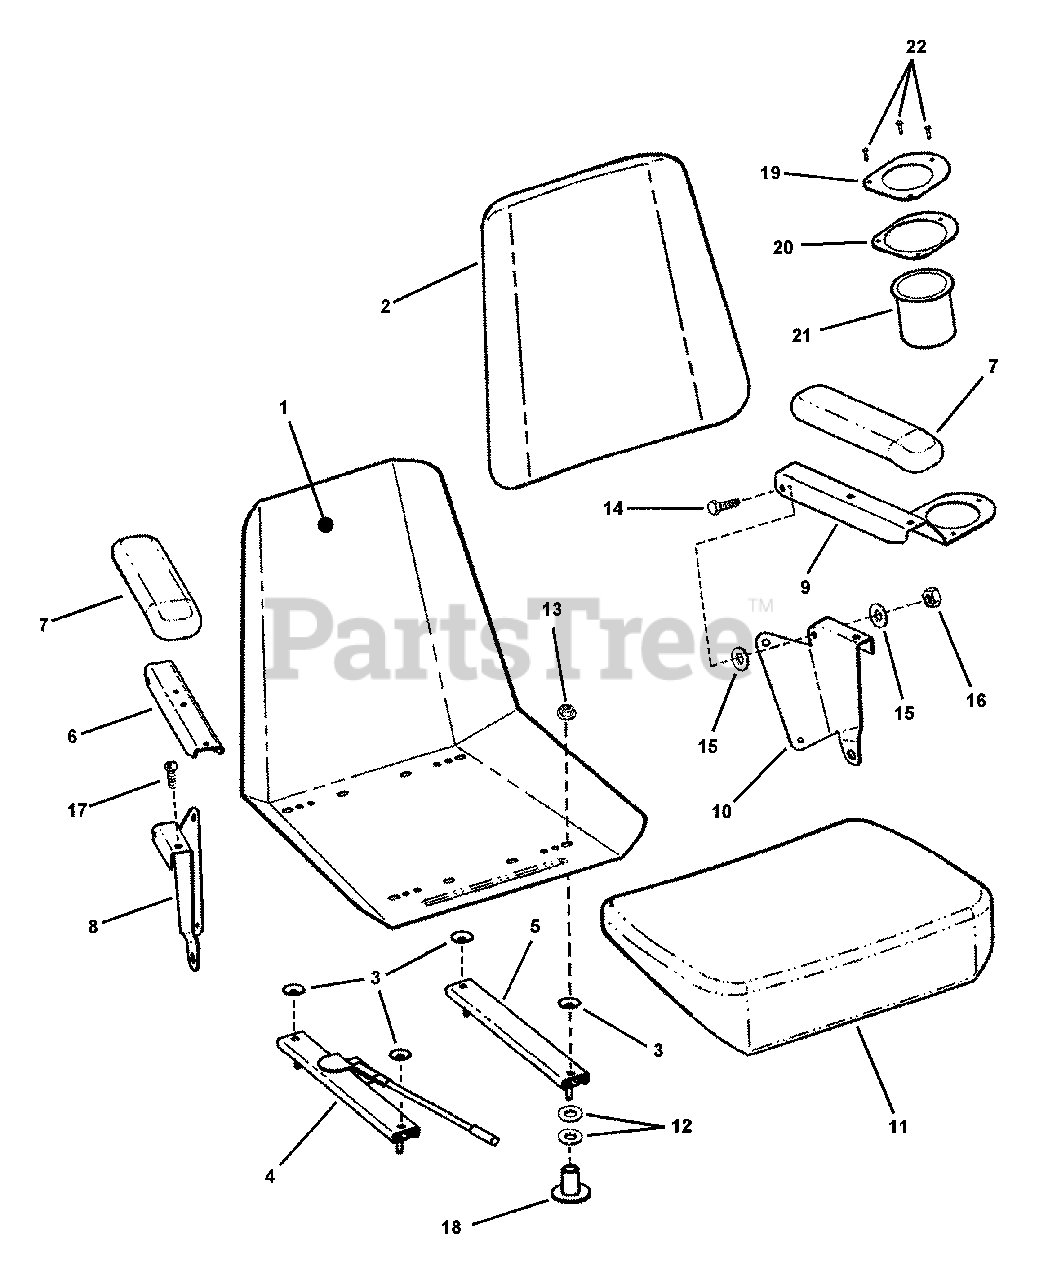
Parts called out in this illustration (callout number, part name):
1	PAN, Seat
2	SEAT CUSHION, Back
3	SPACER, Bell
4	SLIDE ADJUSTER, Seat (w/lock)
5	SLIDE ADJUSTER, Seat (w/o lock)
6	CHANNEL, Armrest
7	PAD, Armrest
8	BRACKET RH, Armrest
9	BRACKET, Armrest Cup Holder
10	BRACKET LH, Armrest
11	SEAT CUSHION, Bottom
12	WASHER, 11/32"
13	NUT, 5/16-18 Hex Flange Lock, Grade 5
14	BOLT, 5/16-18 X 2", GD5
15	WASHER, 3/8: I.D. Poly
16	NUT, 5/16-18 Hex Head Centerlock, Grade B
17	SCREW, 5/16-18 x 1" Slotted Pan Head
18	STUD GUARD
19	COVER, Cupholder
20	SPACER, Cupholder
21	HOLDER, Beverage
22	RIVET, 3/16 Pan Head
